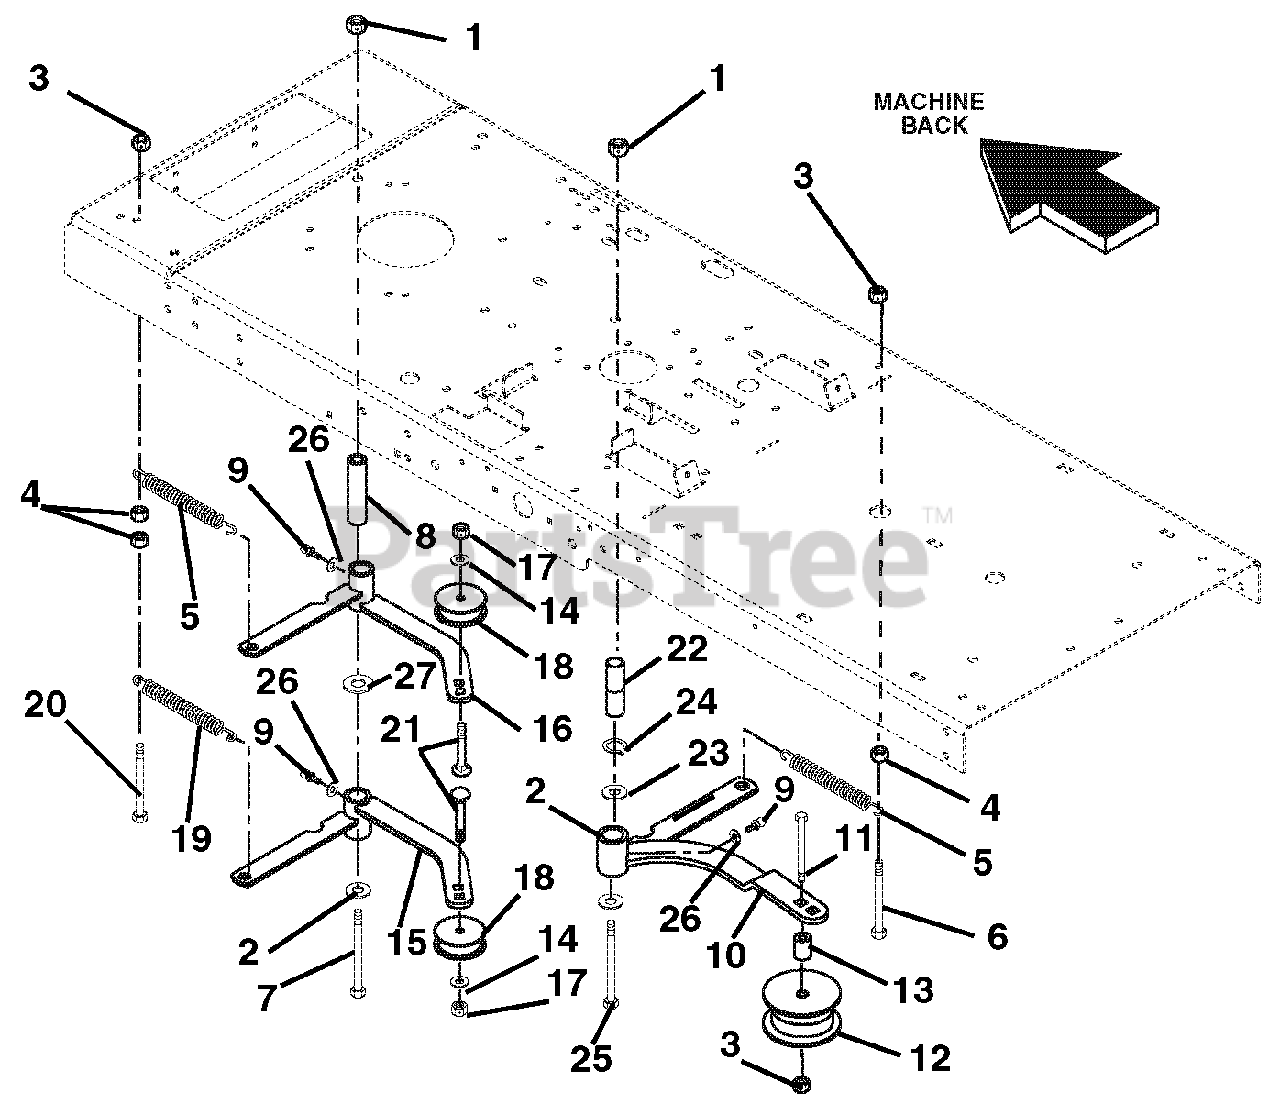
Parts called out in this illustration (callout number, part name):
1	Nut-Locking-Top-Flange .50-13
2	Washer-Flat, Steel .563 x 1.38 x .109
3	Nut-Locking, Center .38-16
4	Nut-Hex .38-16
5	Spring-Extension
6	Bolt-Hex .38-16 x 4.00 Grade 5
7	Bolt-Hex .50-13 x 5.50 Grade 5
8	Spacer-Idler Arm
9	Fitting-Lube .25-28 x .256
10	Weldment-Idler Arm
11	Bolt-Hex .38-16 x 4.50
11	Bolt-Hex .38-16 x 2.50
12	Idler - 4.0 inch Diameter
13	Spacer-Idler 48 inch
14	Washer-Flat, Steel .406 x .812 x .065
15	Idler Arm Weldment Transaxle
16	Weldment-Jackshaft Idler Arm
17	Nut-Jam Lock .38-16
18	Pulley, Idler 4.00
19	Spring, Extension
20	Bolt-Hex .38-16 x 4.50 Grade 5
21	Bolt-Round Head Square Neck .38-16 x 1.50 Grade 5
22	Spacer-Idler
23	Washer-Flat-Steel .88 x 1.25 x .62
24	Ring-Retaining External .875 x .042
25	Bolt-Hex .50-13 x 4.50 Grade 5
26	Washer-Flat-Steel .250 x .562 x .049
27	Washer, .937 x 2.25
